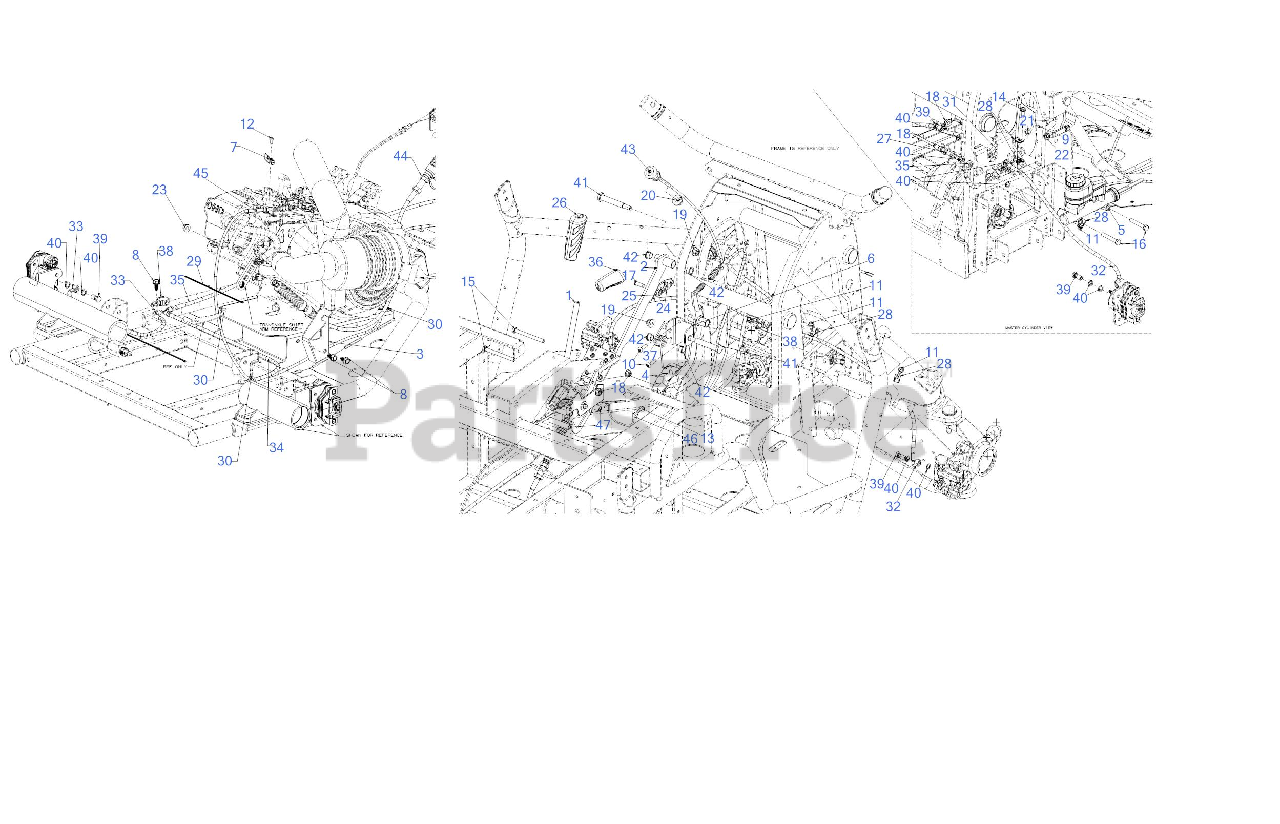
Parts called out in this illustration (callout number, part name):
1	SHIFT CONTROL ASSEMBLY
3	SHIFT BRACKET WELD ASSEMBLY
5	MASTER CYLINDER ASSEMBLY
7	THROTTLE BRACKET
8	SCREW 5/16-18 x .750
9	CARRIAGE BOLT 5/16-18 x 2.00 GR5
10	SCREW 1/4-20 x 1.0
11	SCREW 1/4-20 X.500
12	SCREW M5-.8X10MM SLOT/TORX
13	SCREW M6-1 x .625
14	SCREW 1/4-20 x .750
15	SCREW 5/16-18 x 3.25 GR5
16	SCREW 5/16-18 x 2.0 GR5
17	CLEVIS PIN .312 x 1.0
18	FLANGE LOCK NUT 5/16-18
20	NUT
21	HEX NUT
22	HEX JAM NUT 5/16-24 GR 5
23	HEX FLANGE NUT M8X
24	BOW TIE COTTER PIN 1/4-5/16
25	ADJUSTABLE ROD END
27	BRAKE SWITCH
28	MOUNTING CLAMP
29	TIE CABLE 8.5 LG
30	CABLE TIE
31	BRAKE HOSE (FRONT MASTER CYLINDER)
32	BRAKE HOSE (FRONT)
33	BRAKE HOSE (LEFT HAND REAR)
34	BRAKE HOSE (RIGHT HAND REAR)
35	BRAKE HOSE (REAR MASTER CYLINDER)
36	BRAKE HANDLE GRIP
37	TORSION SPRING
38	TEE FITTING
39	BANJO FITTING
40	BANJO FITTING
41	SHOULDER BOLT
42	NYLINER BEARING
43	CHOKE CABLE 93"
44	SHIFT CABLE 44"
45	THROTTLE CONTROL CABLE 108"
46	CABLE GUIDE ROD
